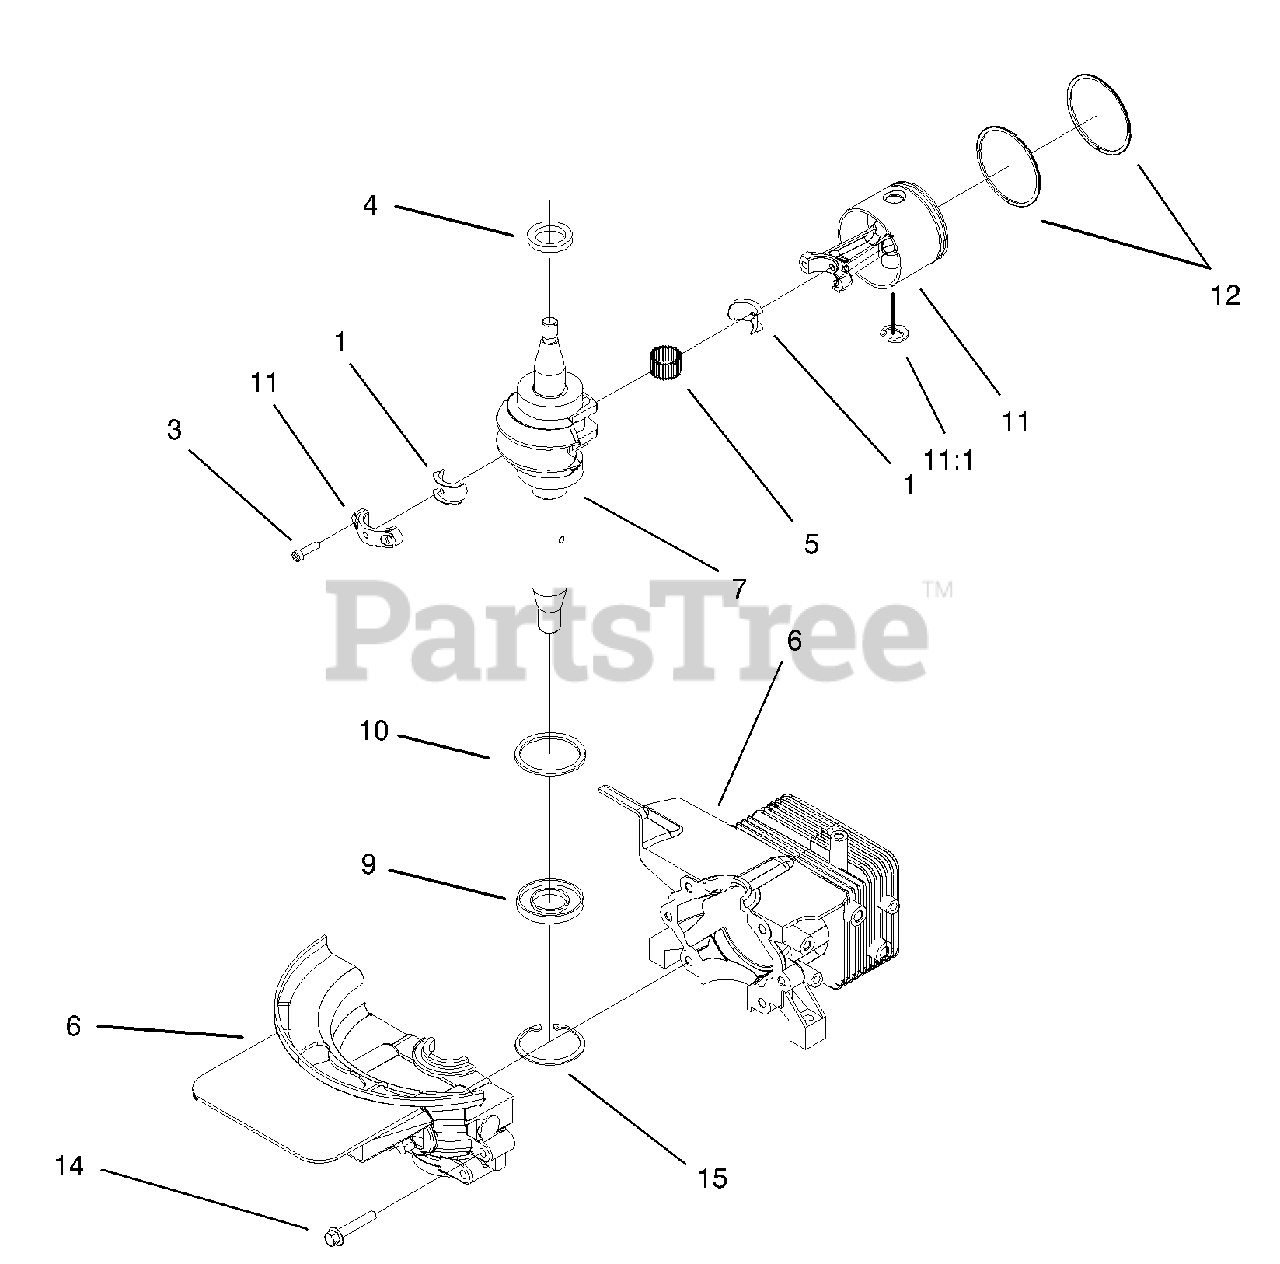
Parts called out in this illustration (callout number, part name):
1	LINER ASM
3	SCREW-HSH
4	SEAL-OIL
5	BEARING-NEEDLE
6	CYLINDER AND CRANKCASE ASM
6	Cylinder And Crankcase ASM
7	CRANKSHAFT AND BEARING ASM
9	SEAL-OIL
10	RING-RET. EX
11	Piston&rod Ay
11:1	RING-RETAINING
14	SCREW-HHF
15	RING-RETAINING
